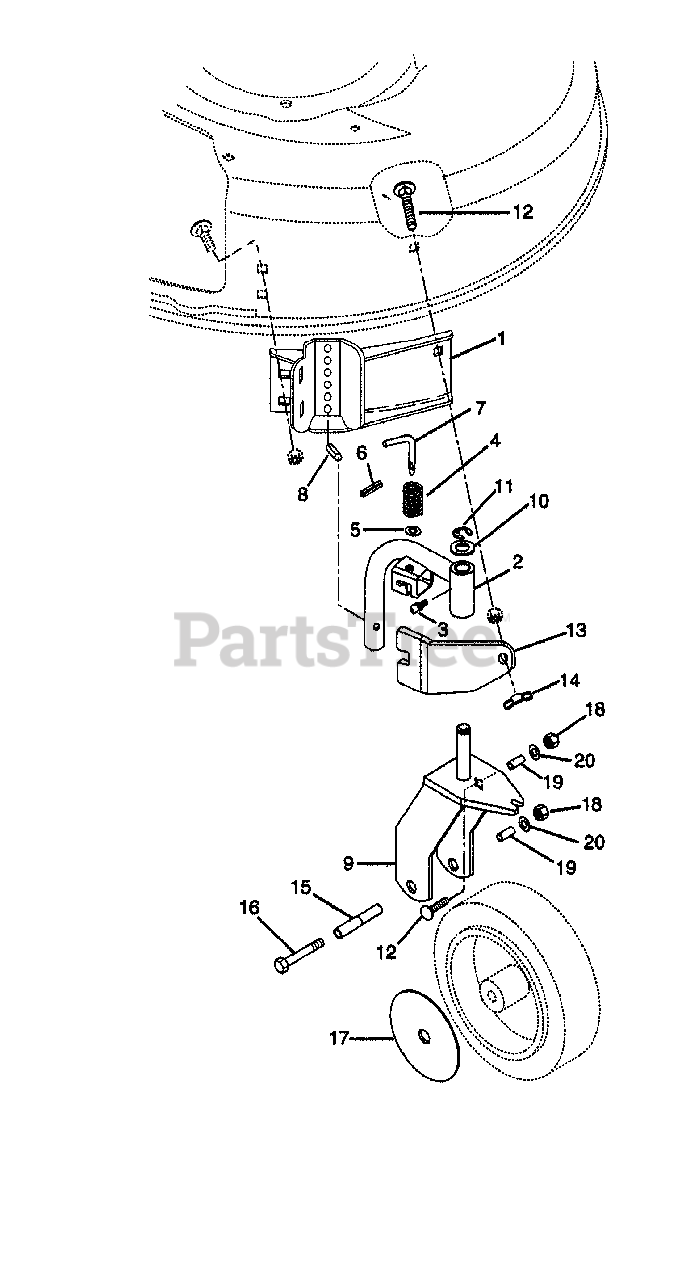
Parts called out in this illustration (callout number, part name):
1	MOUNT-SWIVEL, RH
2	GOOSENECK-W/BSHGS, RH
3	FTG-LUBE .25-28X.256 YWZC
4	SG-COMP .045X.50X1.187
5	@WSHR-FL-STL.406X.812X.065 YWZ
6	PIN-ROLL .156X1.00
7	PIN-LATCH
8	PIN-ROLL .313X1.25
9	YOKE-WHEEL WELD ASSY, RH
10	WSHR-FL-STL .630X1.005X.062 YZ
11	RG-RTNG-EXT .625X.042
12	@BLT-RDHDSQNK .31-18X1.50 G5YZ
13	CLAMP-TUBE, RH
14	NUT-NYLK WING .312-18 YWZC
15	SPACER-SHOULDER,WHEEL
16	@BLT-HEX .31-18X4.00 GR5 YWZC
17	COVER-WHEEL,FRONT SWIVEL
18	@NUT-LK-CTR .31-18 YWZC
19	SPACER .334X.500X.58
20	@WSHR-FL-STL.38X.875X.083 YWZC
